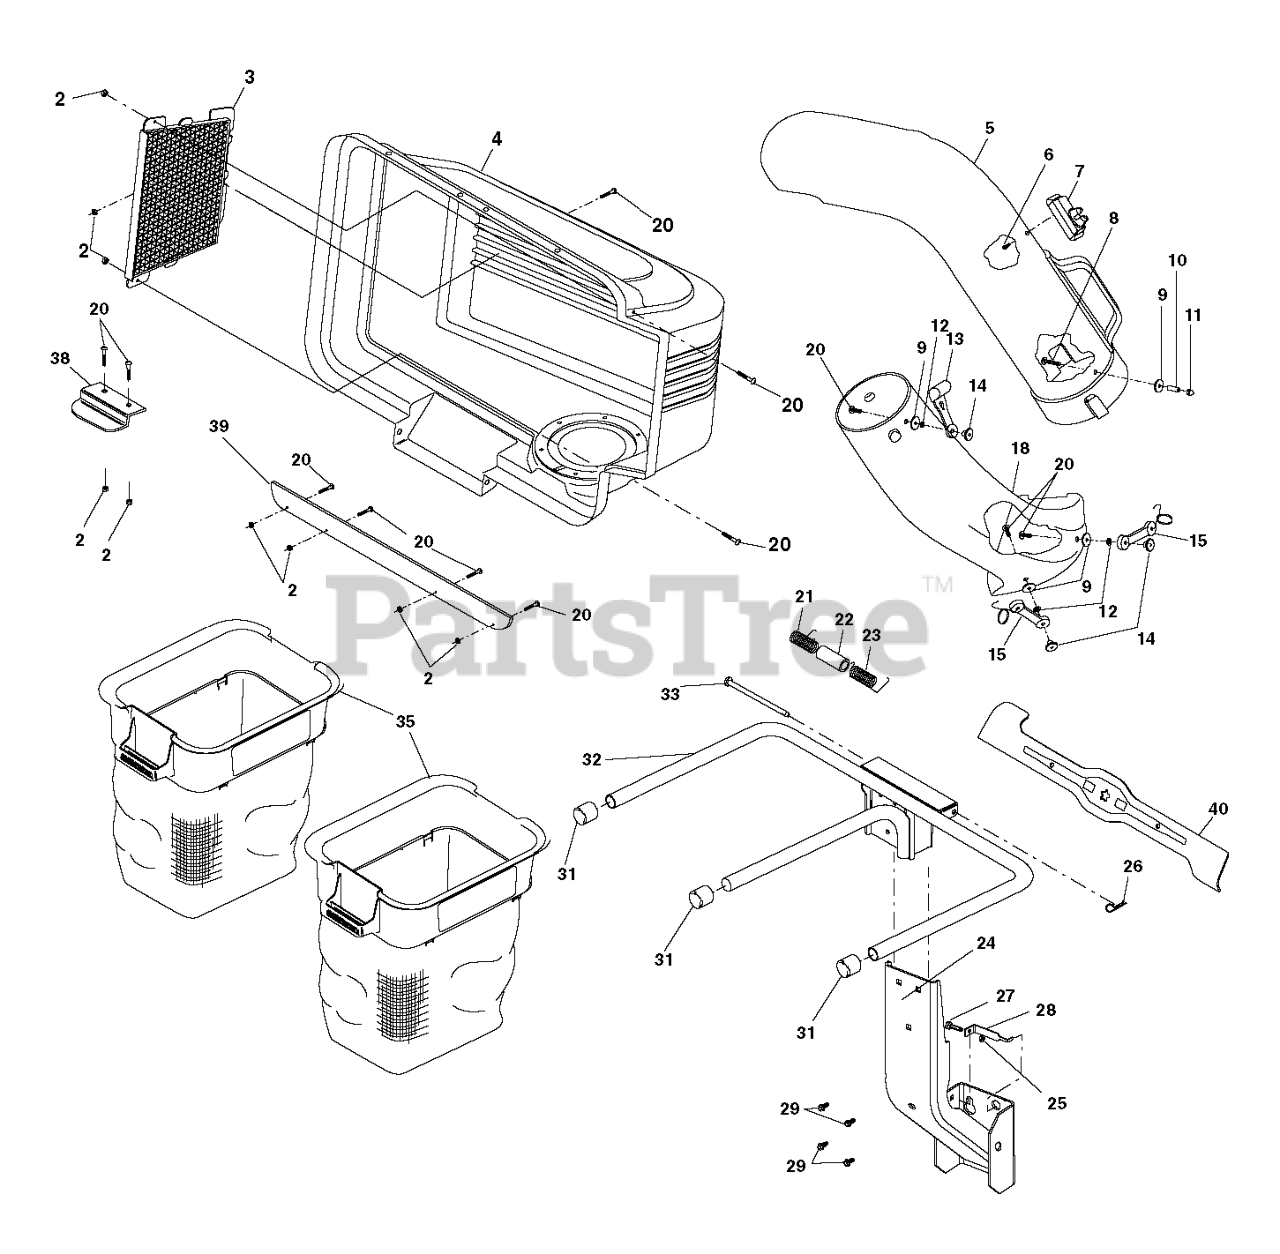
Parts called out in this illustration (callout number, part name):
3	COVER SCREEN
4	COVER.ASM.BAG.W/STRIP
5	CHUTE.UPPER.46"
7	INDICATOR ASM BAG
8	SCREW
9	RP STEEL WASHER
10	SPACER, SPLIT
11	NUT
12	LOCKWASHER #10
13	LATCH.HOOD.
14	WELDNUT
15	LATCH ASSY
18	CHUTE.LOWER.BAGGER.30"(2 2 BR)
20	SCREW
21	SPRING COVER LH
22	SPACER.COVER.BAGGER
23	SPRING COVER RH
24	POST.SUPPORT.BAGGER.BLACK
25	LOCKNUT.NYLOC.1/4-20
26	RETAINER-SPRNG RB
28	STOP BRACKET, BAGGER 2 BIN
29	SHOULDER BOLT 5/16-18TT
31	PLUG, TUBING END
32	FRAME.ASM.BAGGER.2BIN.QC42B
33	BAGGER.HINGE.PIN
35	CONTAINER BAG, SOFT
38	LATCH CER38
39	STRIP.REINFORCE.BAGGER.2BIN.BL
40	BLADE, 30" BAGGER
